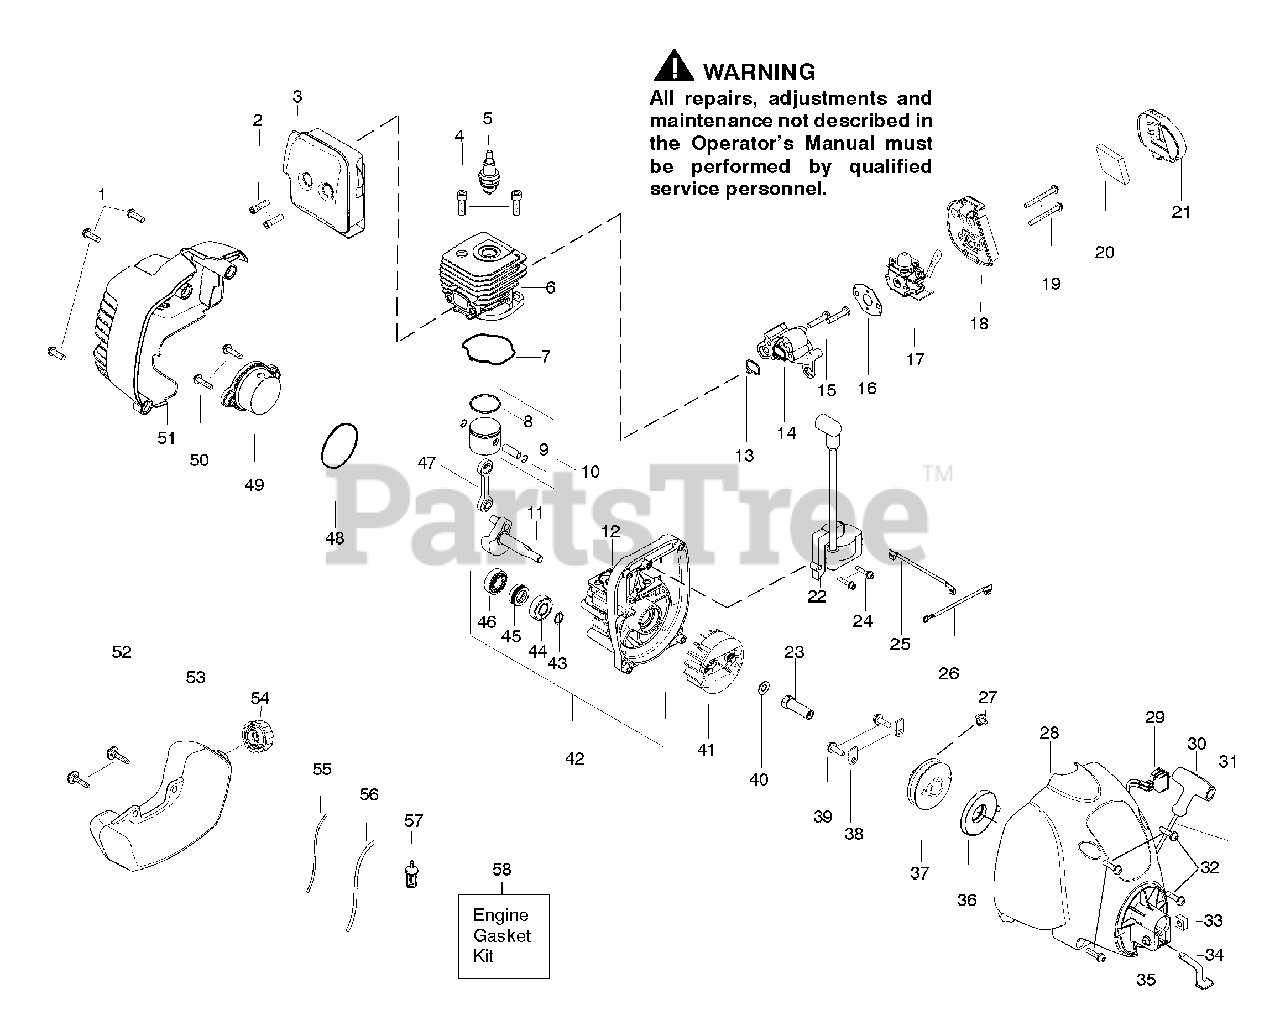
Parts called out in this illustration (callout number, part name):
2	Bolt-Muffler
3	Assy-Muffler/Shield
4	Screw-Cylinder
5	Spark Plug
6	Cylinder
7	Seal-Cylinder
8	Piston Ring
9	Retainer-Piston Pin
10	Kit - Piston
11	Assy-Crankshaft
12	Assy-Crankcase
13	Seal-Cyl/Carb.
14	Adapter-Carb.
16	Gasket-Carb.
17	Kit-Carb. Zama
17	Kit-Carb. Walbro
18	Air Box
20	Foam-Air Filter
21	Cover-Air Box
22	Ignition Module
23	Coupling-Drive
25	Assy-Leadwire
26	Assy-Ground Wire
28	Assy.-Fan Hsg
29	Kit-Switch
30	Handle-Starter
31	Kit - Rope
32	Screw
34	Clip-Spring
36	Spring-Starter
37	Kit-Pulley-Starter
38	Retainer-Pulley
40	Washer-Flat
41	Assy-Flywheel
42	Assy-C'case & C'shaft
43	Retain. Ring-C'shaft
44	Outer Bearing
45	Seal-C'case
46	Inner Bearing
47	Assy-Connecting Rod
48	O-Ring-C'case
49	Assy-Plug
51	Shroud-Rear Green
51	Shroud-Rear Black
52	Retainer-Tank
53	Assy-Fuel Tank
54	Assy-Fuel Cap
55	Kit-Fuel Line
56	Kit-Fuel Line
57	Assy-Fuel Pickup
58	Kit-Engine Gasket
